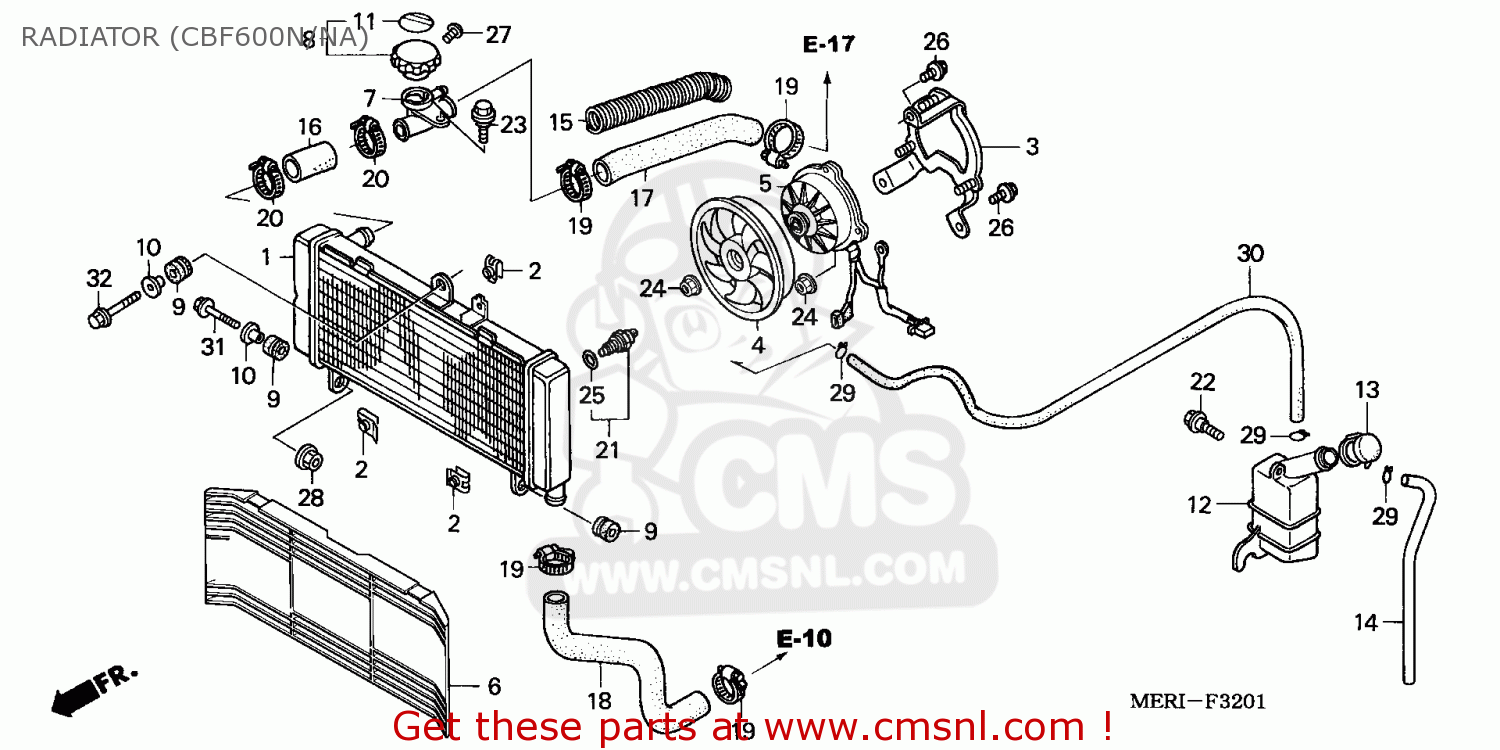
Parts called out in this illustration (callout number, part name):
1	RADIATOR COMP
2	SET,NUT
3	SHROUD COMP
4	FAN COMP,COOLING
5	MOTOR ASSY,FAN
6	GRILL,RADIATOR
7	FILLER NECK
8	CAP COMP.RAD.
9	RUBBER,RAD.MOUNT
10	COLLAR,RAD MT
11	SEAL,RAD.CAP
12	TANK,RESERVE
13	CAP,RESERVE TANK
14	TUBE,5.3X1500
15	PROTECTOR,RAD.UP
16	HOSE,RAD UPPER A
17	HOSE,RAD UPPER B
18	HOSE RAD.LWR.
19	CLAMP,HOSE,3037
20	CLAMP,HOSE 30-37
21	SWITCH ASSY.,THER
22	BOLT,FLANGE,6MM
23	BOLT,FLANGE 6MM
24	NUT,SERRAT,5MM
25	O-RING 13.5X1.4
26	BOLT,WASH,6X14
27	SCREW,TAPPING 3X8
28	NUT,FLANGE,6MM
30	TUBE 5.5X550
31	BOLT,FLANGE,SH,6X25
32	BOLT,FLANGE,6X28
